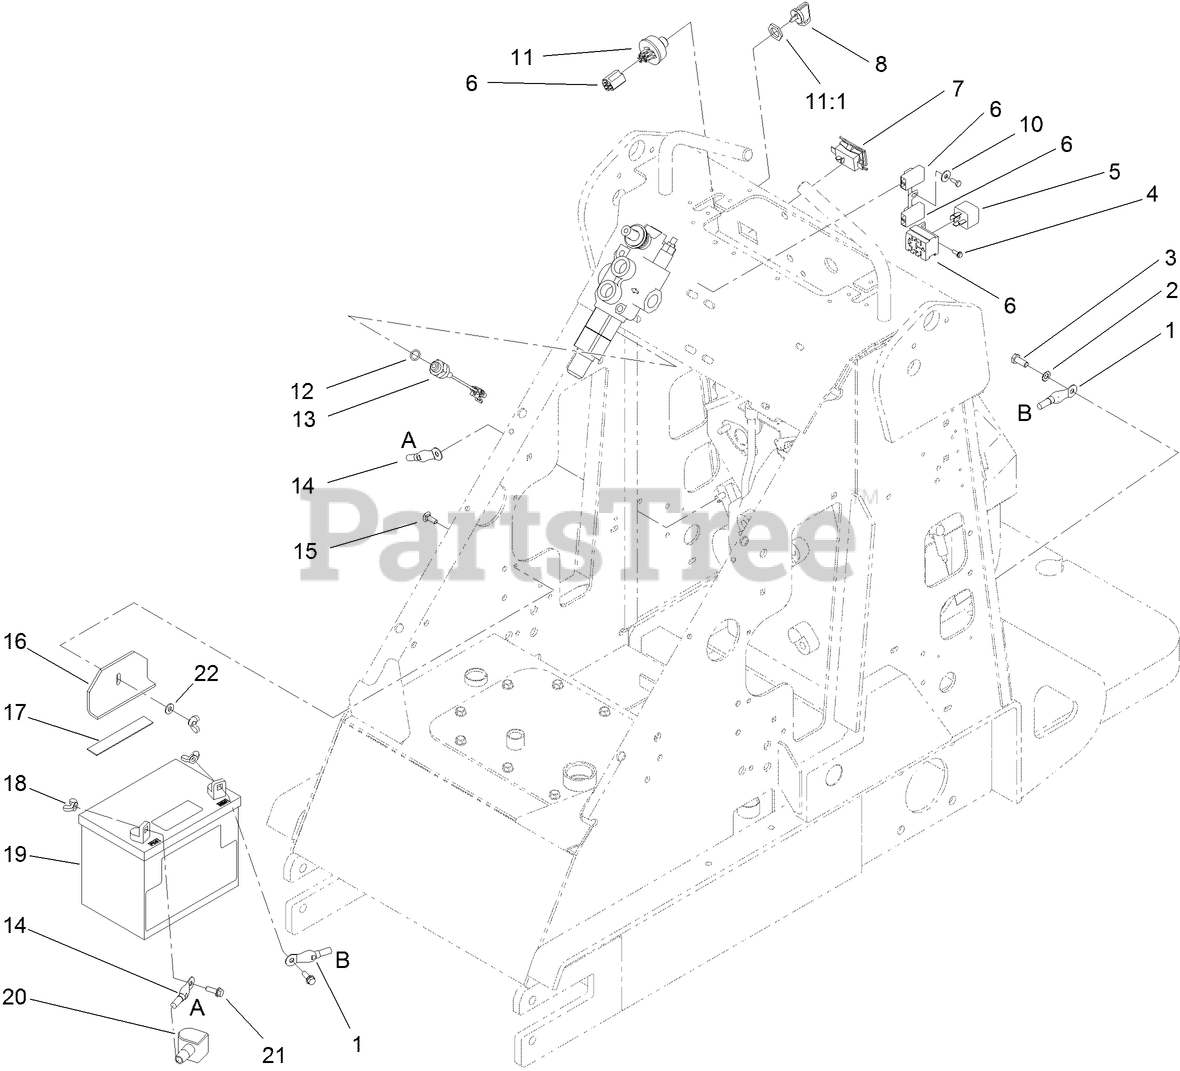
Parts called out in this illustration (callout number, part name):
1	CABLE-BLACK
2	WASHER-LOCK
3	SCREW-HH
4	SCREW-HWHTF
5	RELAY
6	HARNESS-ELECTRICAL
7	METER-HOUR
8	KEY-IGNITION
10	WASHER-PLAIN
11	KEY SWITCH ASM
11:2	WASHER-LOCK
12	O-RING
13	SWITCH-BALL
14	WIRE-21 INCH
15	SCREW-CARR
16	CLAMP-BATTERY
17	PAD-FOOTREST
18	NUT-WING
19	BATTERY-DRY
20	BOOT-TERMINAL, RED
21	SCREW-HHF
22	WASHER-FLAT
